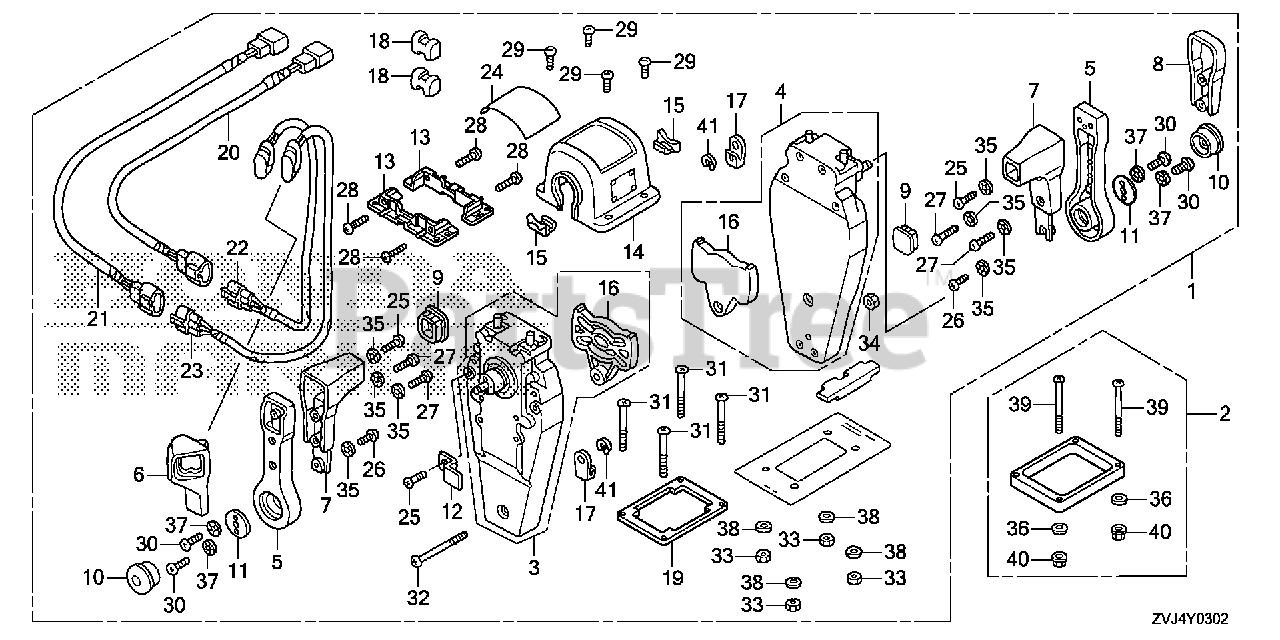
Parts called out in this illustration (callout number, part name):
1	BOX KIT, REMOTE CONTROL (TOP MOUNT DUAL)(R)
2	SPACER KIT, REMOTE CONTROL BOX (TOP MOUNT DUAL)
3	HOUSING ASSY., L. (INNER) (TOP MOUNT)
4	HOUSING ASSY., R. (INNER) (TOP MOUNT)
5	HANDLE, REMOTE CONTROL
6	COVER, L. GRIP
7	GRIP, REMOTE CONTROL HANDLE
8	COVER, DUAL GRIP
9	CAP, GRIP
10	BUTTON, THROTTLE
11	PLATE, HANDLE
12	PLATE, CABLE CLAMP
13	BRACKET, REMOTE CONTROL HOUSING
14	HOUSING, DUAL REMOTE CONTROL BOX
15	HOUSING, LEAD
16	PLATE, DWELL
17	TERMINAL, CABLE
18	SPACER, CABLE CLAMP
19	GASKET, DUAL
20	SUB-HARNESS ASSY., POWER TRIM-TILT (A)
21	SUB-HARNESS ASSY., POWER TRIM-TILT (B)
22	SWITCH ASSY., POWER TRIM-TILT (A)
23	SWITCH ASSY., POWER TRIM-TILT (B)
24	MARK, REMOTE CONTROL (DUAL)
25	SCREW, PAN (5X16)
26	SCREW, PAN (5X10)
27	SCREW, PAN (5X20)
28	SCREW, PAN (5X18)
29	SCREW, PAN (4X10)
30	SCREW, PAN (6X18)
31	SCREW, PAN (5X40)
32	SCREW, PAN (5X55)
33	NUT, HEX. (5MM)
34	NUT, HEX. (5MM)
35	WASHER, LOCK (5MM)
36	WASHER, PLAIN (5MM)
37	WASHER, LOCK (6MM)
38	WASHER, PLAIN (5MM)
39	SCREW, PAN (5X65)
40	NUT, HEX. (5MM)
41	E-RING (6MM)
